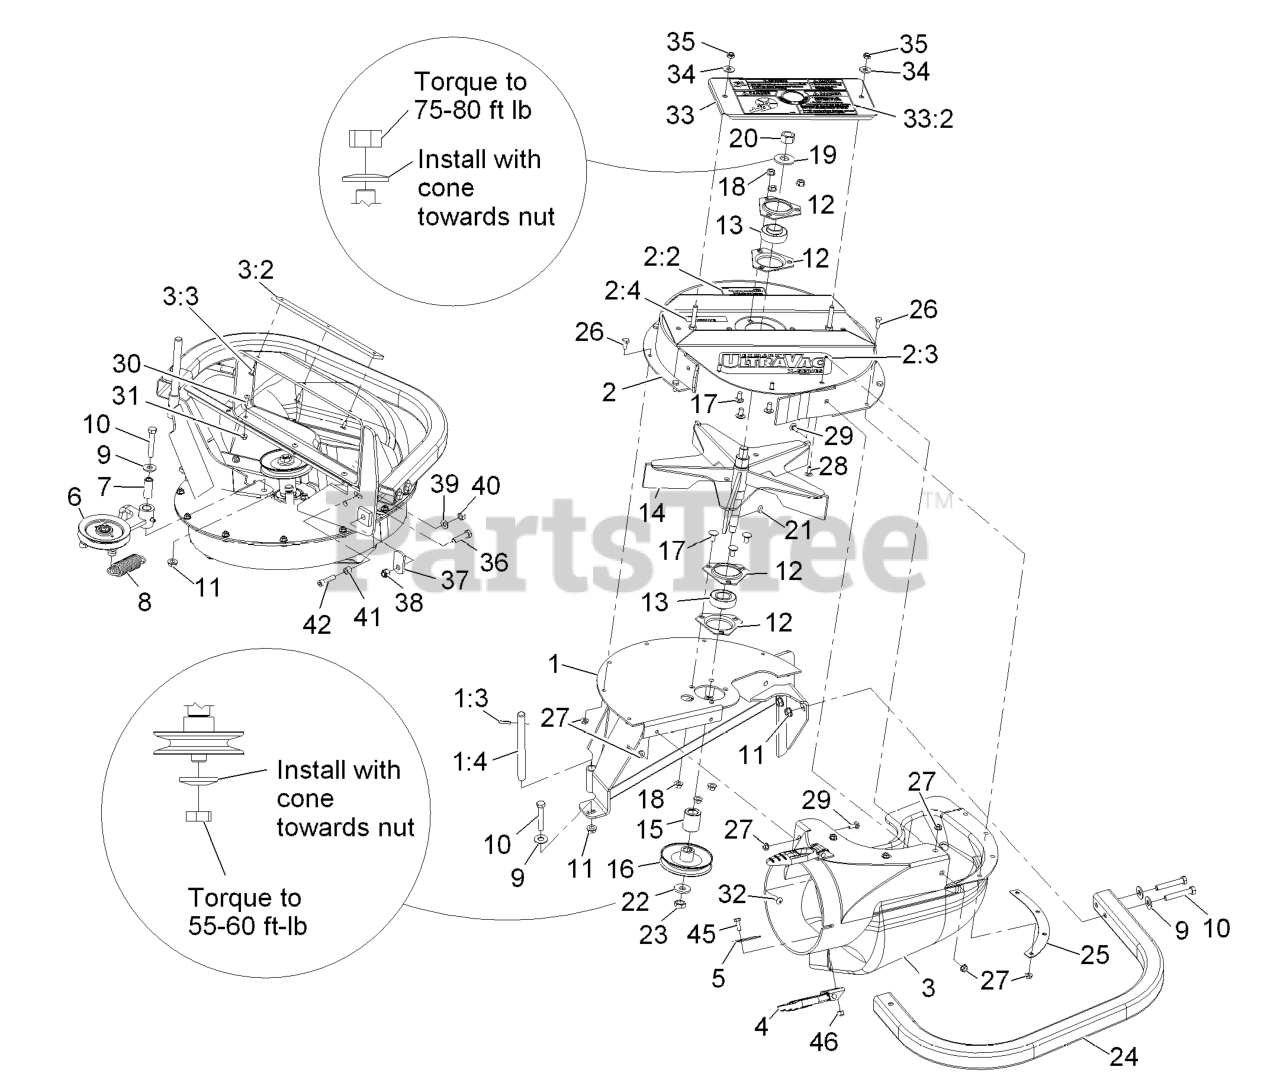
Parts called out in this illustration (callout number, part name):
1	WLD,FRAME LG BLOWER
1:3	PIN-ROLL
1:4	SHAFT-CATCHER, GRASS
2	ASM-UPPER HOUSING LARGE
2:2	DECAL,WEIGHT
2:3	DECAL-ULTRA VAC X-SERIES
2:4	DECAL-COVER, MISSING
3	ASM,BLOWER CHUTE LZ
3:2	PLATE,REINFORCEMENT LARGE
3:3	RIVET-BLIND
4	LATCH-RUBBER
5	PLATE-BACKING
6	Asm, Idler
7	BUSHING
8	SPRING-IDLER
9	WASHER-FLAT
10	SCREW-HH
11	NUT-HHF, WHIZ
12	HOUSING-FLANGE
13	BEARING
14	IMPELLER
16	SHEAVE
17	SCREW-CARR
19	WASHER-SPRING
20	NUT-HEX
21	KEY-WOODRUFF
22	WASHER-SPRING
23	NUT-JAM
25	PLATE-BACKING, BLOWER
26	SCREW-HH
28	SCREW-CARR
29	BOLT-CARR
30	SCREW-HEAD, TRUSS
33	COVER, BEARING
33	ASM, BEARING COVER
33:2	DECAL-WARNING, BLOWER
34	WASHER-FLAT
35	NUT-LOCK, NI
36	SCREW-HH
37	LATCH-CATCHER, GRASS
38	NUT-LOCK, NI
39	WASHER-SPRING
40	NUT-HEX
41	BUSHING, LOCATOR
42	SCREW-HSH
45	SCREW-HH
46	NUT-LOCK, NI
